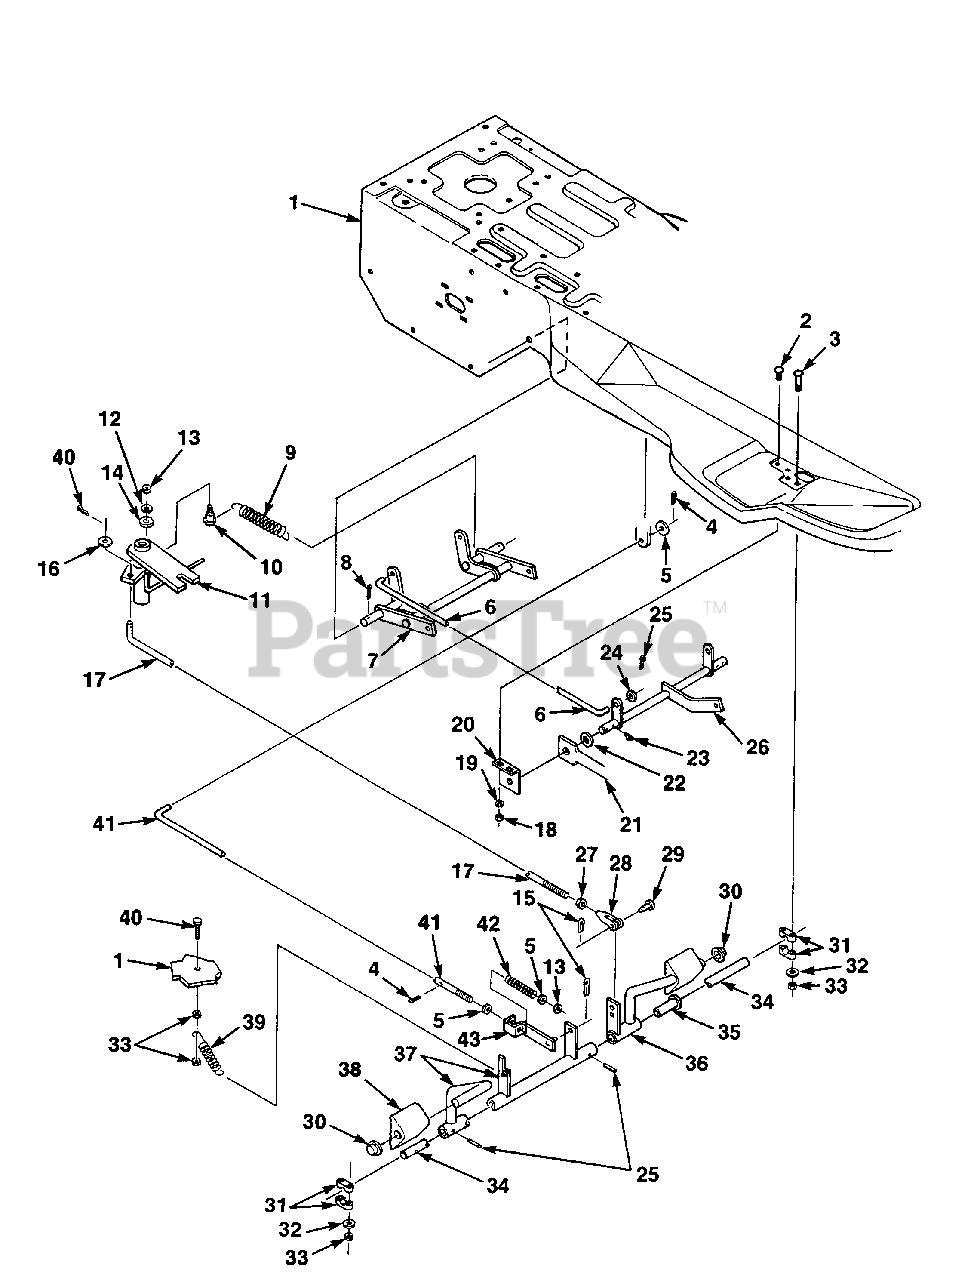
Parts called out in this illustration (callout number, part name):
2	BOLT-Carr. 1/4-20 x 5/8
3	BOLT-1/4-20 x 1 1/2
4	PIN-Cotter
5	WASHER
6	ROD-Deck lift
7	BRACKET-Rear hanger
8	PIN-Cotter
9	SPRING-Extension
10	BOLT-5/16-18 shoulder
11	ARM-Pivot
12	WASHER-Lock 5/16
13	NUT-Hex 5/16-18
14	WASHER-Flat 5/16
15	PIN-Cotter
16	WASHER-1/4
17	ROD-Clutch
18	NUT-1/4-20
19	WASHER-Lock 1/4
21	SUPPORT-Front axle
22	WASHER-Flat
23	PIN-Cotter
24	WASHER-Plain
25	PIN-Cotter
26	HANGER-Front
28	YOKE-Clutch rod
29	PIN-Clevis
32	WASHER-Flat 1/4 reg.
33	NUT-Centerlock hex- 1/4-20
34	PEDAL SHAFT
36	PEDAL-Clutch
37	PEDAL-Brake
38	PEDAL-Rubber
40	SCREW-1/4-20 x.625
41	ROD-Brake
42	SPRING-Brake
43	BRACKET-Brake spring
